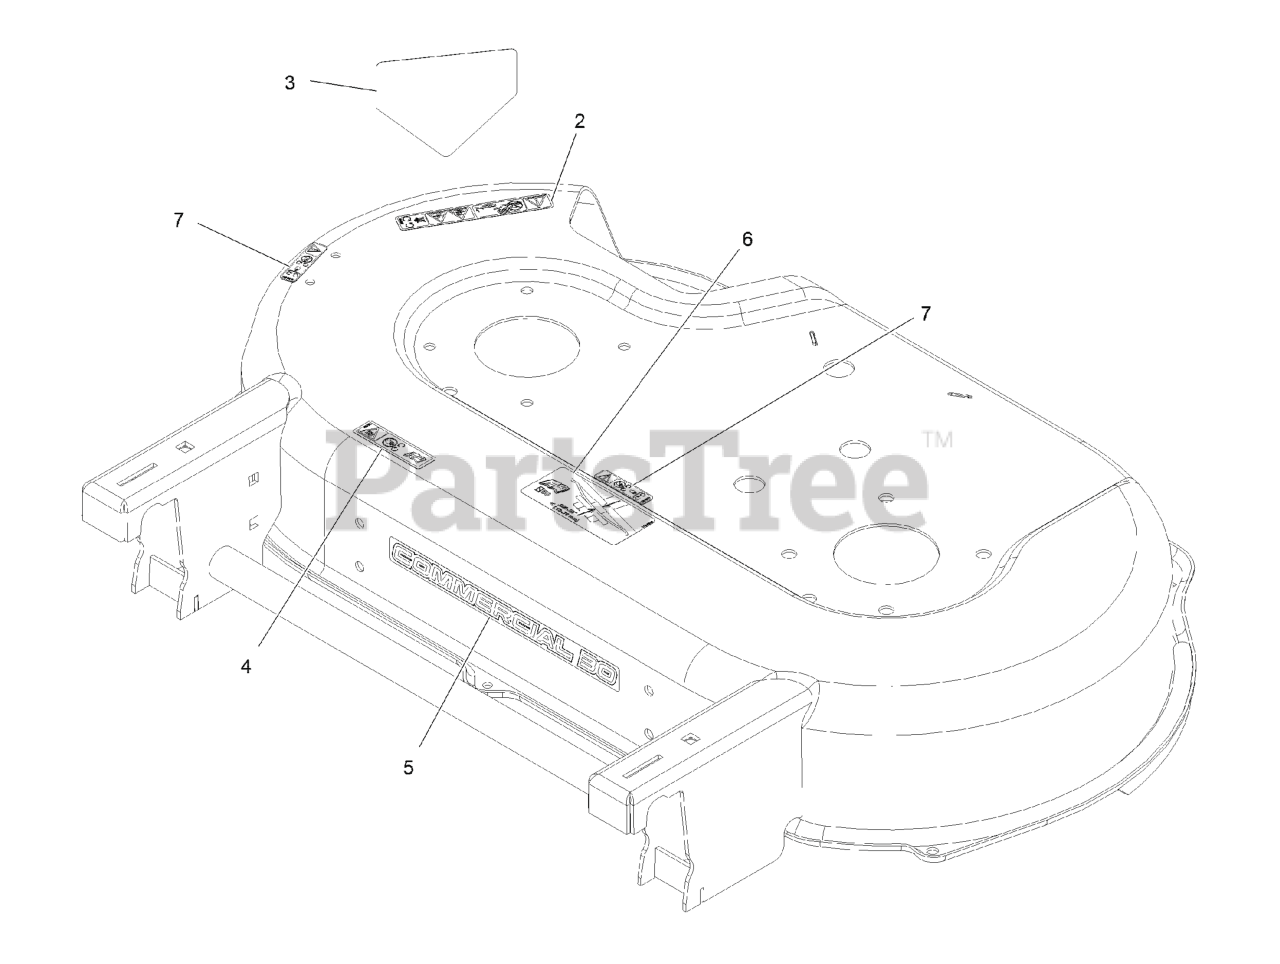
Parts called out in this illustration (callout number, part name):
2	DECAL-DANGER
3	DECAL-DANGER
4	DECAL-WARNING
5	DECAL-COMMERCIAL 30
7	DECAL-WARNING
